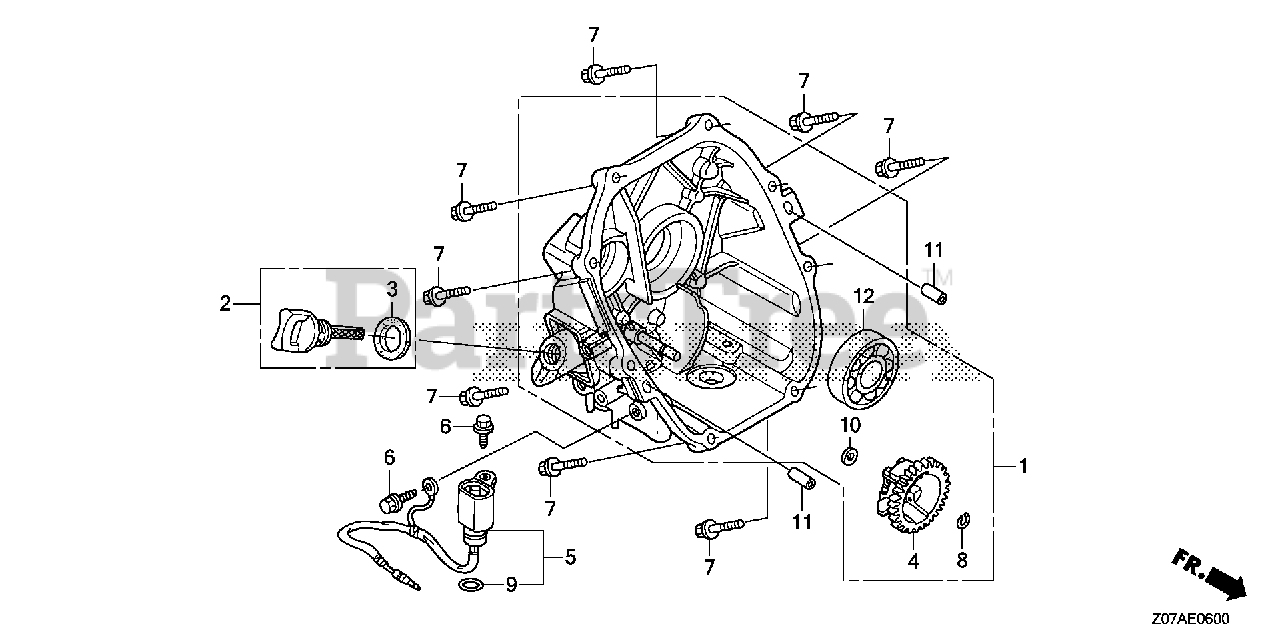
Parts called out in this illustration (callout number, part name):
1	COVER ASSY., CRANKCASE
2	CAP ASSY., OIL FILLER
3	GASKET, OIL FILLER CAP
4	HOLDER, GOVERNOR WEIGHT
5	SWITCH ASSY., OIL LEVEL
6	BOLT, FLANGE (6X14) (CT200)
7	BOLT, FLANGE (6X25) (CT200)
8	CLIP, GOVERNOR HOLDER
9	O-RING (11.8X2.4)
10	WASHER, PLAIN (6MM)
11	PIN, DOWEL (8X20)
12	BEARING, RADIAL BALL (6204)
